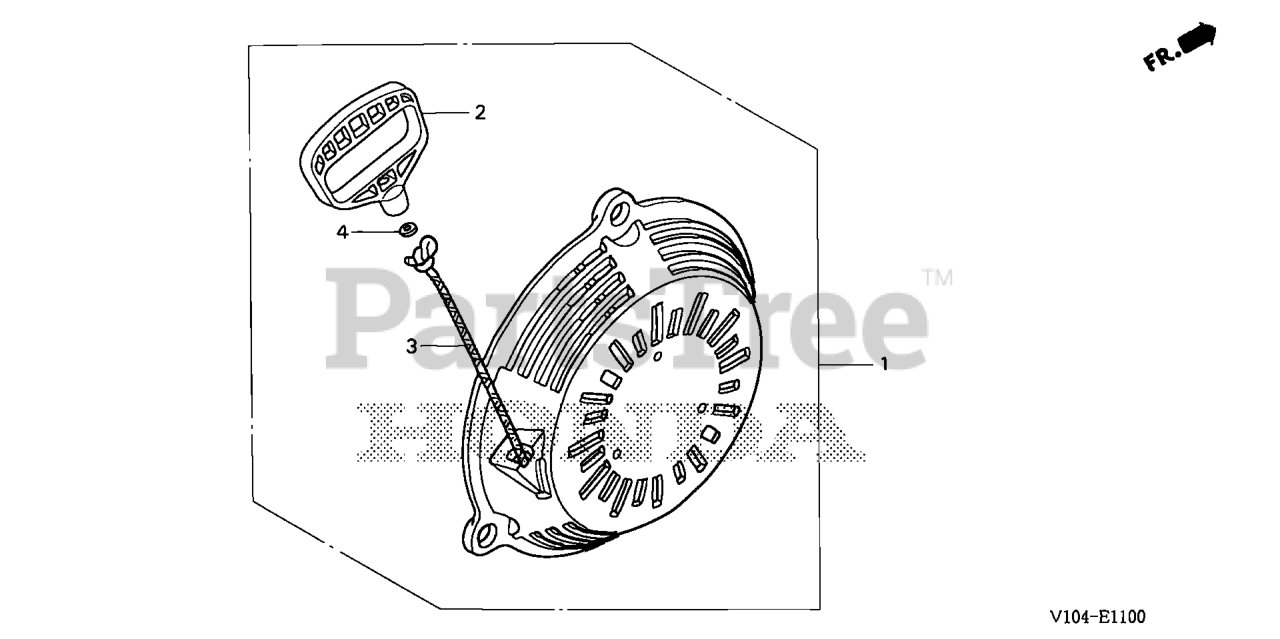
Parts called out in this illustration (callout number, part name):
1	STARTER ASSY., RECOIL
2	GRIP, STARTER
3	ROPE, RECOIL STARTER
